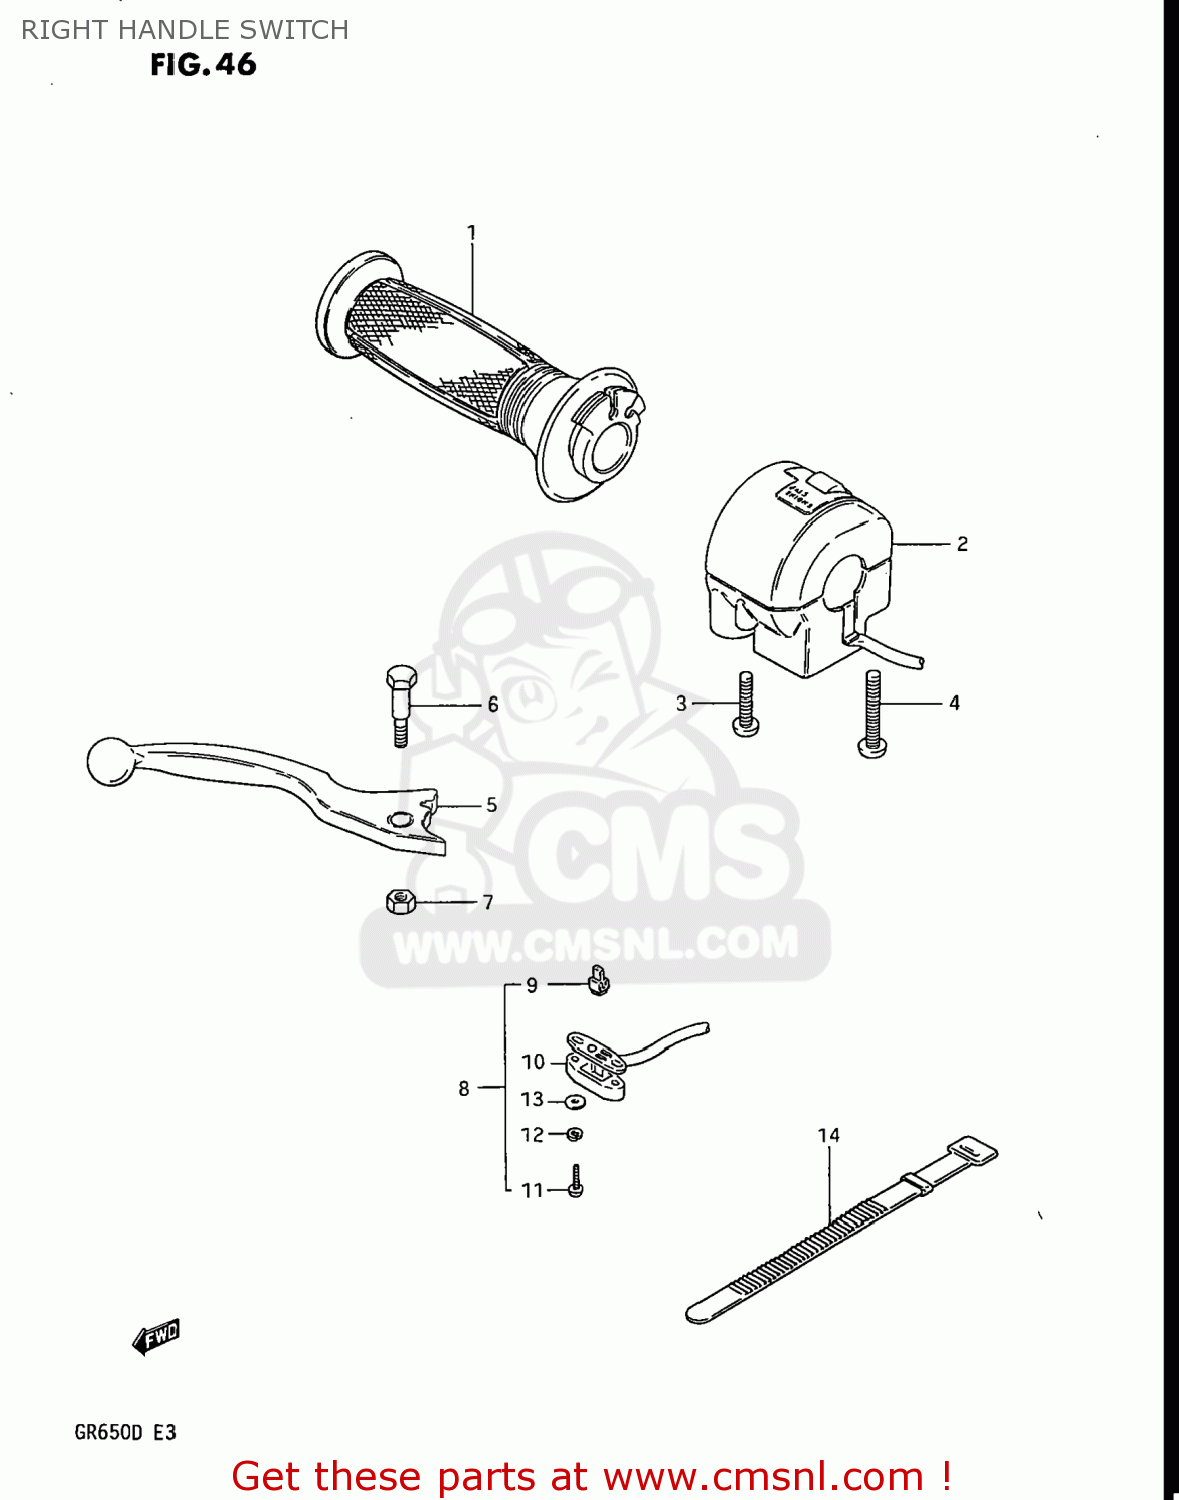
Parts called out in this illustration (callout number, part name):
1	GRIP,THROTTLE
2	SWITCH ASSEMBLY,HANDLE,RIGHT
3	SCREW
4	SCREW
5	LEVER,BRAKE
6	BOLT
7	NUT 6MM
8	SWITCH ASSEMBLY
9	CONTACT,SWITCH
10	COVER,FR BK TERMINAL BASE
11	SCREW
12	LOCK WASHER
13	WASHER
14	CLAMP(L:120)
